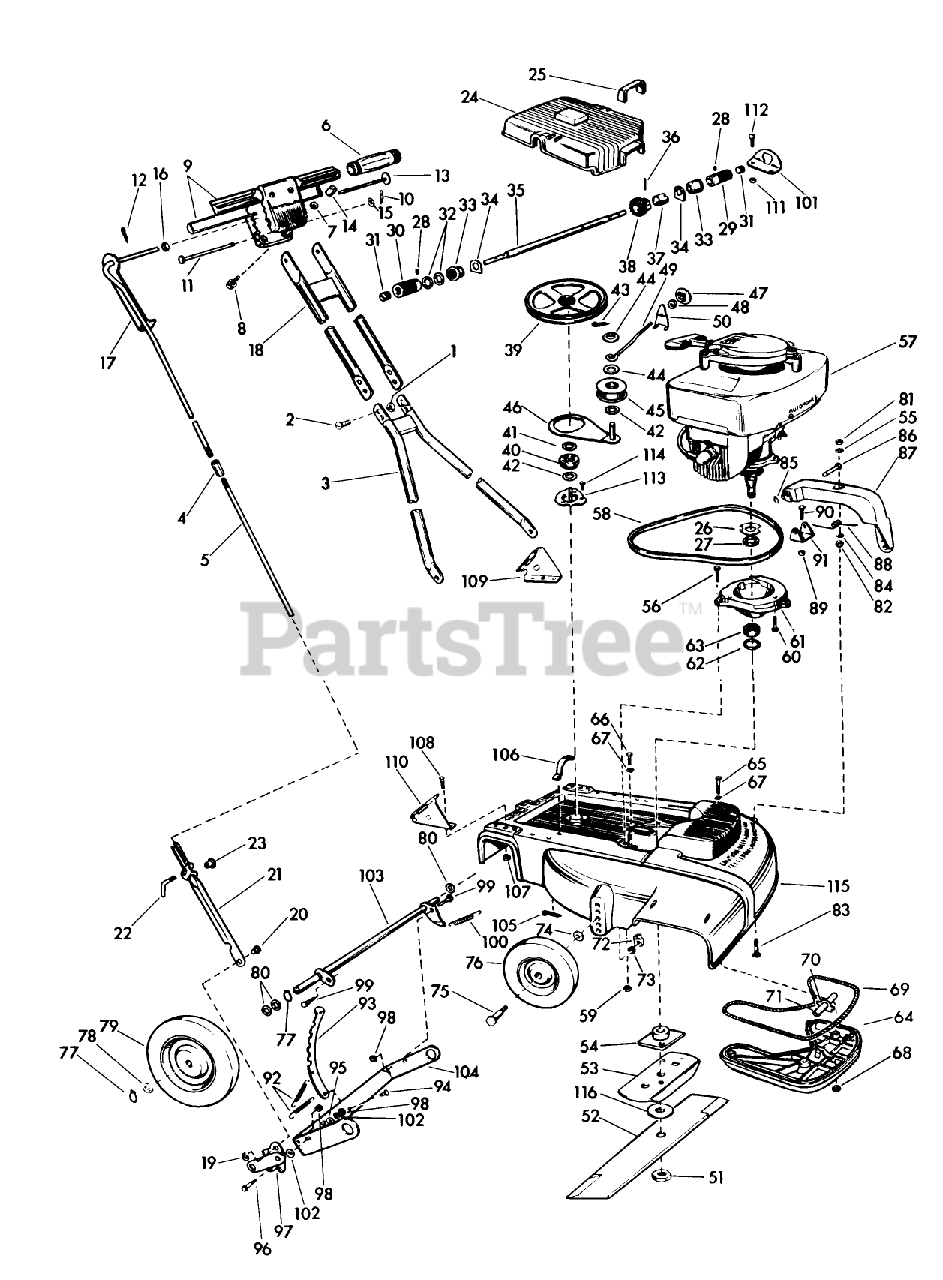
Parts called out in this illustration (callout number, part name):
1	STOP NUT
7	Nut-Handle Bar Screw
12	Pin-Cotter
15	Washer-Handle Pivot
16	Washer-Control Rod
24	Cover-Pulley, 18"
24	Cover-Pulley, 21"
29	Roller-Drive Shaft, Left
31	GREASE PLUG
35	Drive Shaft, 18"
40	Felt-Oiler (Cup)
47	Knob-Speed Change
48	Nut-Lock
49	Rod-Speed Change
50	Lock-Speed Change
51	NUT-BLADE
52	Blade-21"
54	PLATE AND COLLAR ASM
55	Washer-Level Ride, Fiber
58	Belt-V, 29" Class 3L, Fractional H.P. 18" Model
66	Bolt-Muffler
67	Gasket-Muffler Bolt
68	LOCKNUT E
70	Gasket-Internal Tube
71	Tube-Internal Muffler
73	WASHER, LOCK
77	RETAINING RING
81	STOP NUT
82	Nut-Level-Ride Bolt
83	Bolt-Level-Ride Arm
84	Washer-Level Ride Arm
85	Hair Pin-Level Ride Arm
86	Pin-Level Ride Arm
87	Arm-Level Ride
88	Spring-Level Ride Arm
89	STOP NUT
90	Screw-Level-RideArm Bracket
91	Bracket-Level Ride Arm
93	Lever-Height Adjustment
96	BOLT RB&W
98	STOP NUT
99	BOLT RB&W
102	WASHER S
104	Bracket-Axle, 18"
111	STOP NUT
